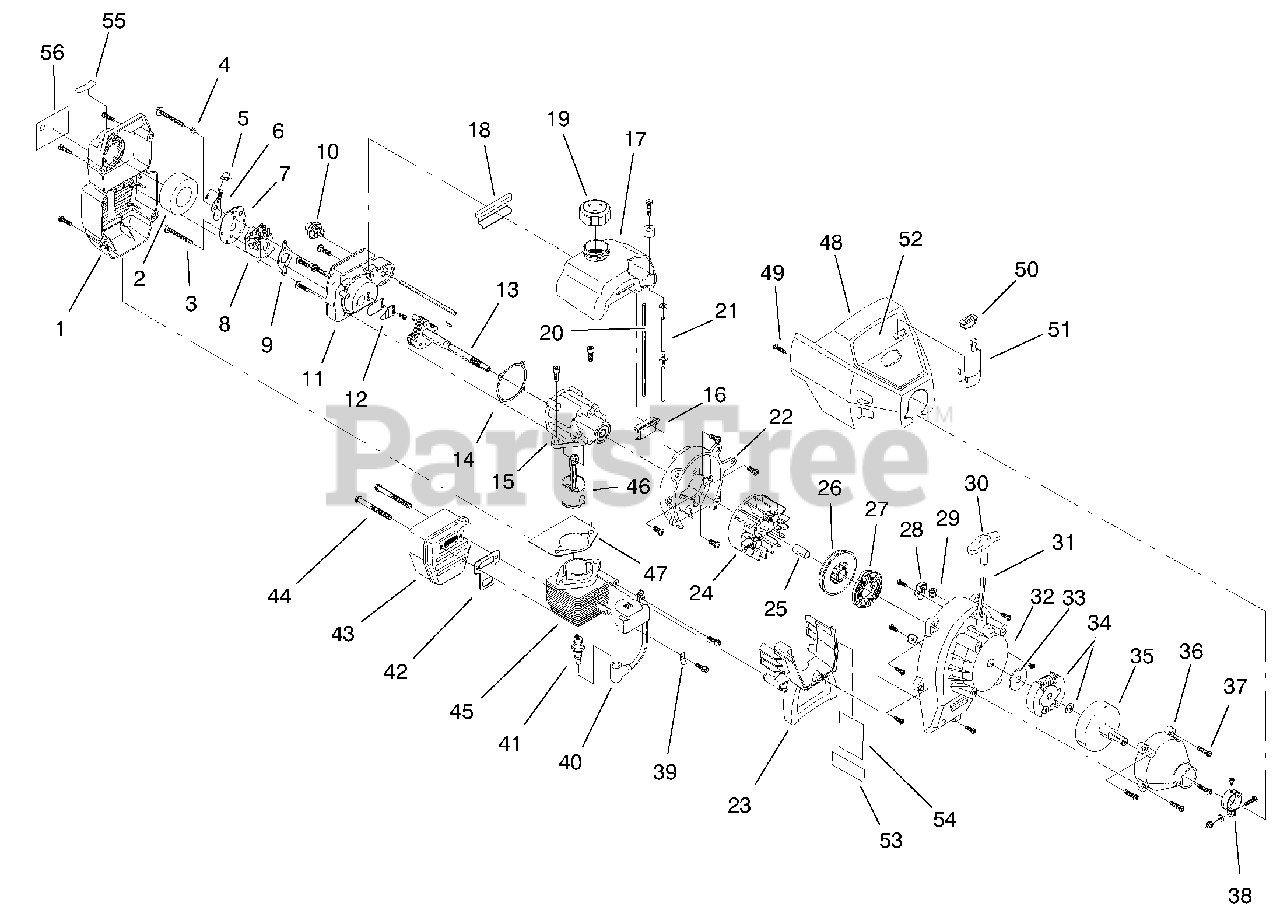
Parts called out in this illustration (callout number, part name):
1	Cover ASM (Includes Ref# 2)
2	Filter-Air Cleaner
3	Carburetor Mounting Screw ASM
4	Washer-Wavey
5	Choke Lever ASM (Includes Ref #6)
6	Choke Knob & Screw
7	Choke Lever & Plate (Includes Ref #5)
8	Carburetor ASM
9	Gasket-Carburetor
10	Primer & Hose ASM
11	Carburetor Mount ASM
12	Reed ASM
13	Power Shaft ASM
14	Gasket-Carburetor Mount
15	Crank Case ASM (Includes Ref #13)
16	Front Mounting Pad
17	Fuel Tank ASM (Includes Ref #19-21)
18	Rear Mounting Pad
19	Fuel Cap ASM
20	Fuel Return Line
21	Fuel Line Assembly
22	Shroud ASM
23	Shroud Extension & Stand
24	Flywheel ASM
26	Recoil Pulley
27	Recoil Spring
28	Pulley Retainer ASM
29	Rope Guide
30	Pull Handle
32	Housing-Starter ASM
33	Washer-Clutch
34	Rotor-Clutch ASM
35	Drum-Clutch ASM
36	Cover-Clutch ASM
37	Screw-Clutch Cover
38	Upper Clamp ASM
39	Ground Tab
40	Module ASM
41	Spark Plug
42	Gasket-Exhaust
43	Muffler ASM (Includes Ref #44)
44	Muffler Mounting Bolt
45	Cylinder ASM
46	Piston & Rod ASM
47	Gasket Cylinder
48	Cover-Engine
49	Screw-Engine Cover
51	Lead Wires
52	Decal-Toro Housing
53	Decal-Warning, Hot Surface
54	Decal-Carb
55	Decal-Choke Position
56	Decal-Fuel & Oil Mix
